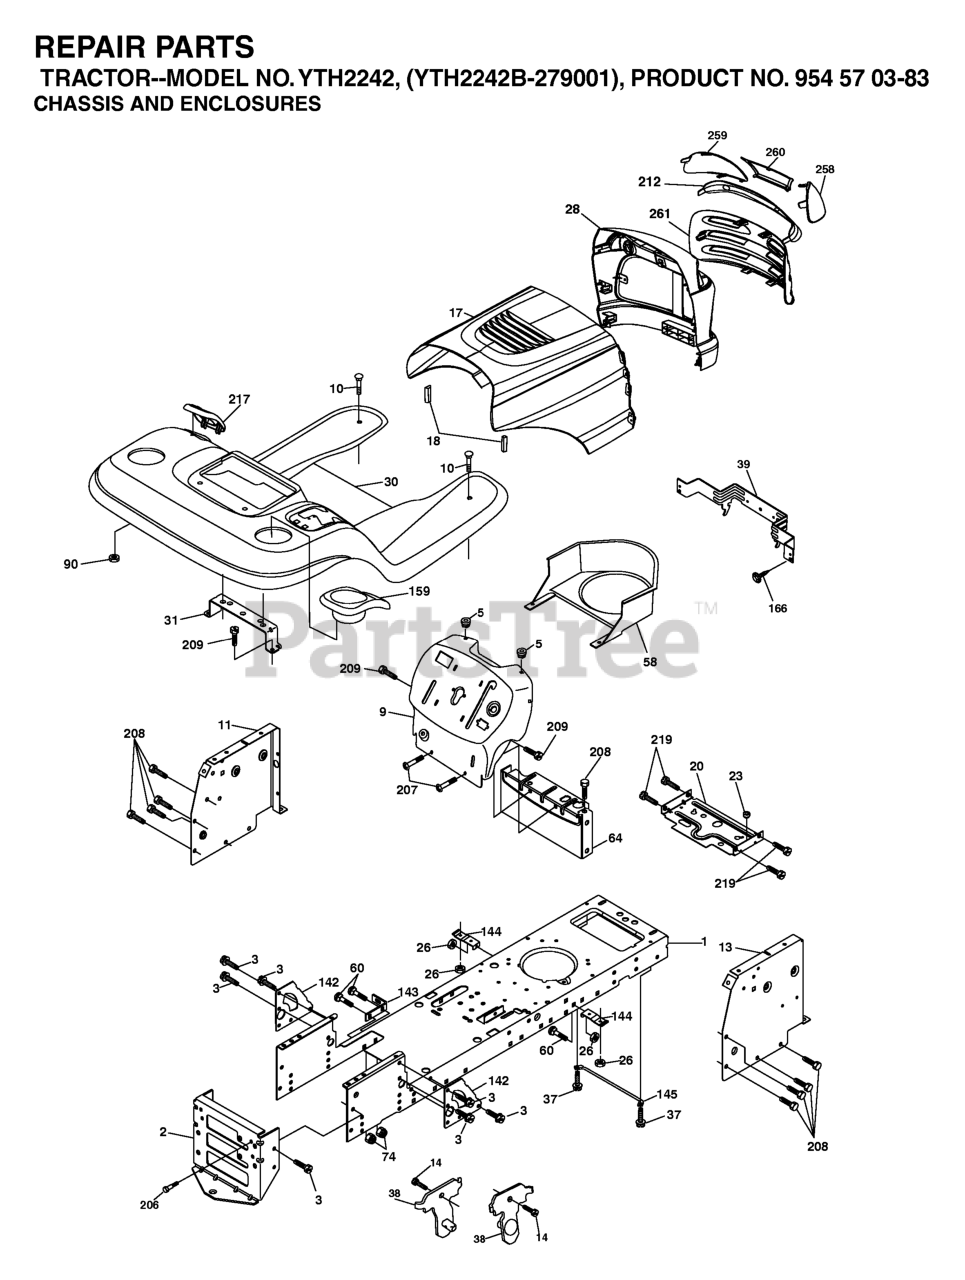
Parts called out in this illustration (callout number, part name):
1	CHASSIS STAMPING
2	DRAWBAR, 12GA
3	SCREW 3/8-16X3/4
5	BUMPER.RUBBER.HOOD
9	DASH(SUBS)
10	BOLT D
11	PANEL.DASH.LH.LTX
13	PANEL ASM, DASH RH
17	HOOD
18	BUMPER.HOOD.LARGE.1.75"
20	PLATE MTG.BATTERY/FUEL TANK
23	BUSHING.SNAP.NYL.BLK.
26	NUT
28	GRILL/LEN.ASM.DL.HUSQ
30	FENDER
31	BRACKET.SUPPORT.FENDER
37	Screw 5/16-18 x 1/2 Hex, Self Tapping 5/16-18 x 1/2
38	BRACKET.ASM.PIVOT.MOWER.REAR
39	BRACKET PIVOT LASER
60	Bolt - Rd. Hd. Sq. Neckiage 3/8 16 x 3/4
64	DASH LOWER
90	NUT.PUSH.3/16
142	PLATE REINFORCEMENT
143	BRACKET, SWAY BAR
144	BRKT, FOOT REST
145	ROD PIVOT CHASSIS/HOOD
159	GREY CUP HOLDER
166	SCREW
206	SHOULDER BOLT 5/16-18TT
207	SCREW, 5/16-18 X 1/2
208	SCREW 3/8-16X1/2
209	SCREW, 3/8-16X3/4
212	INSERT.LENS.REFLECTIVE
217	CONSOLE FUEL WINDOW
219	SCREW
258	LENS LH
259	LENS LH
260	COVER.LENS.HUSQ.( HAVE GRAY)
261	INSERT GRILLE
